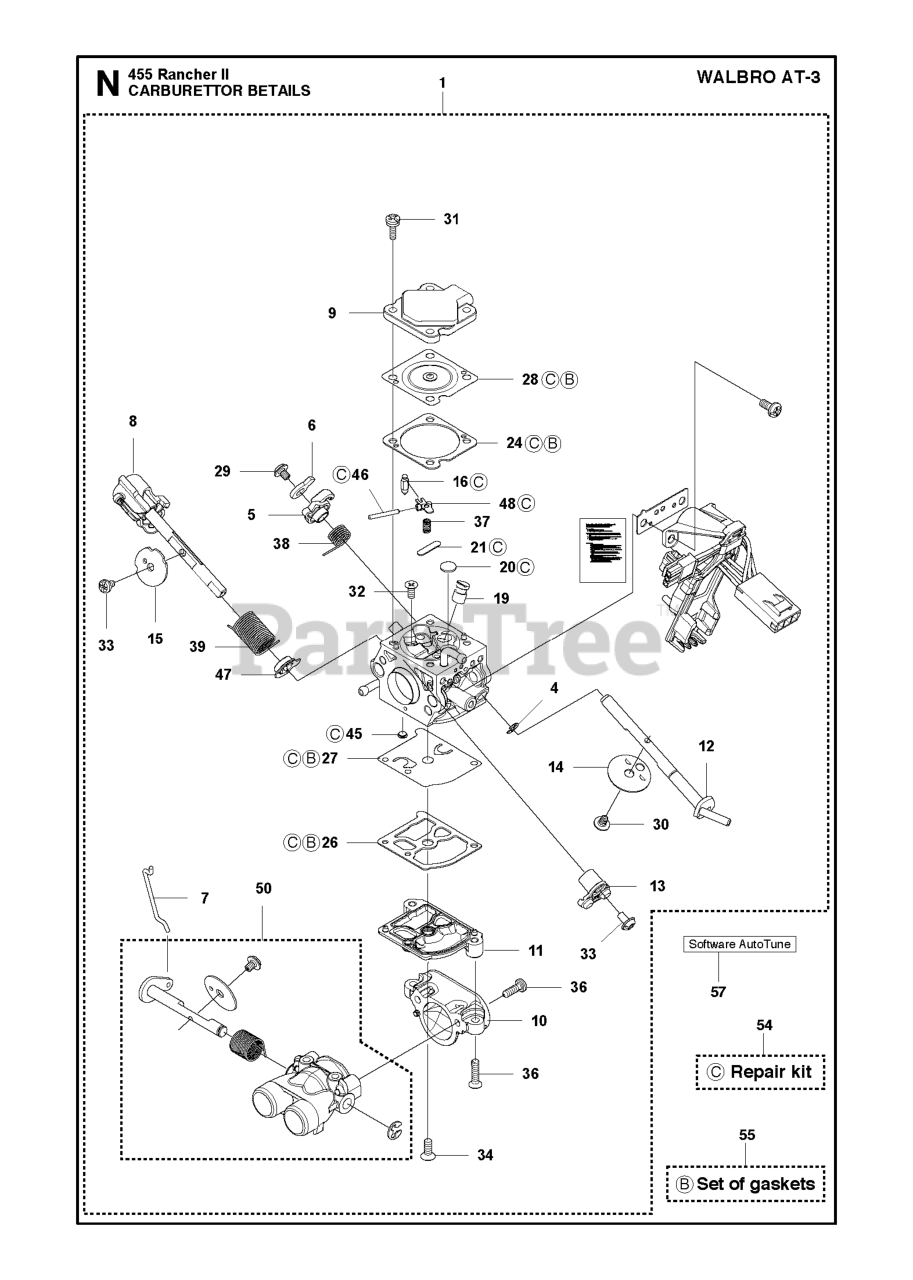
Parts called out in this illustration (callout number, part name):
1	CARBURETOR
8	THROTTLE LEVER
12	SHAFT ASSY
13	THROTTLE SHAFT
15	THROTTLE VALVE
16	INLET NEEDLE
19	MAIN NOZZLE
20	PLUG WELCH
28	DIAPHRAGM ASSY
30	SCREW
45	FUEL INLET SCREEN
46	FULCRUM PIN
50	THROTTLE VALVE ASSY
54	REPAIR KIT
55	GASKET KIT
